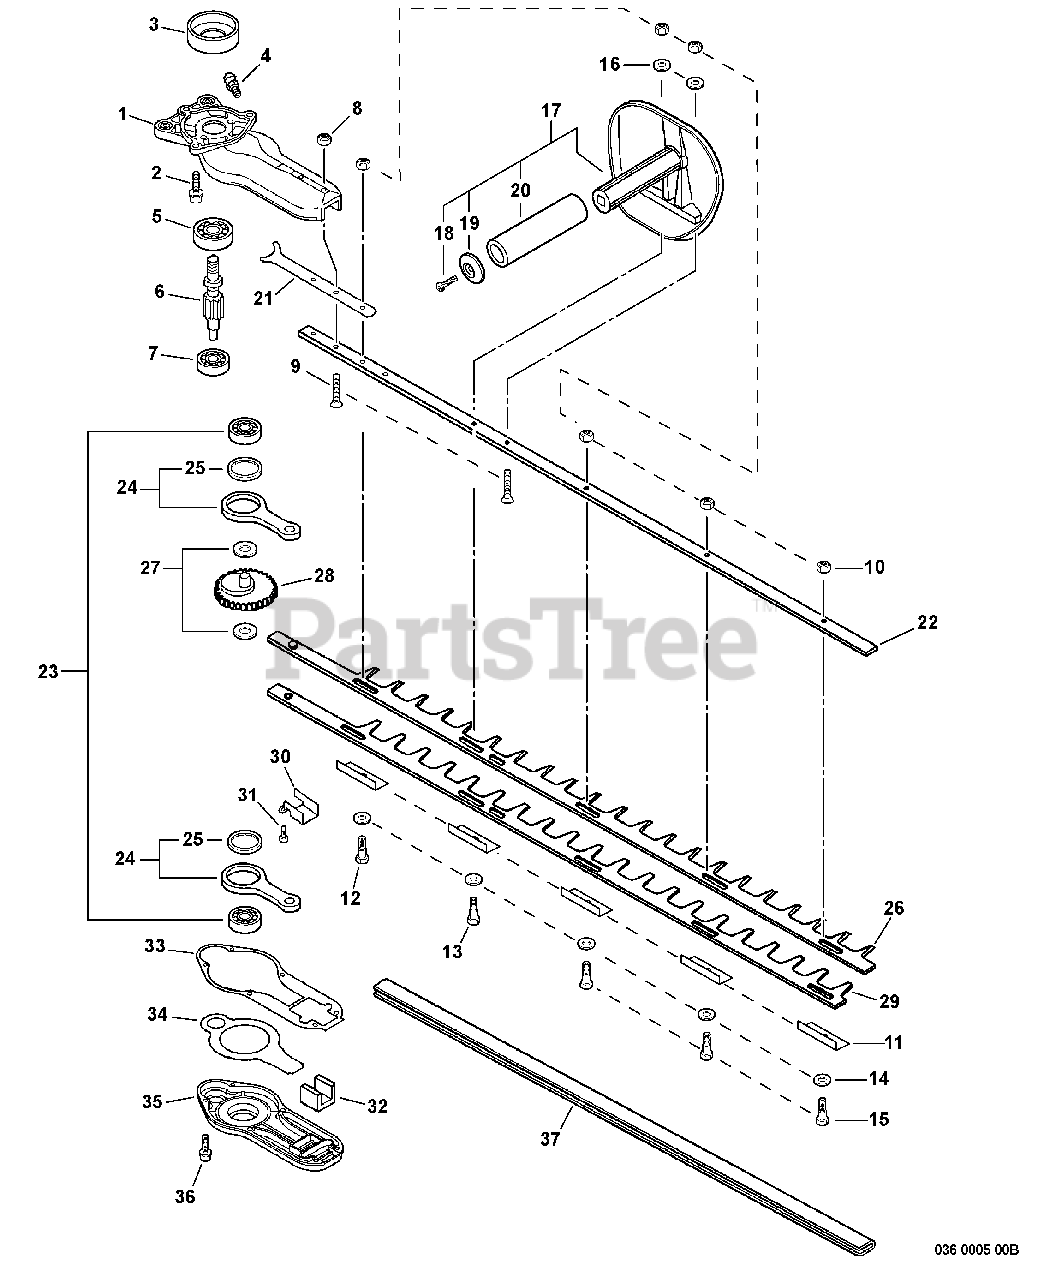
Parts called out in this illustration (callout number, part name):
1	CASE, GEAR - UPPER
2	BOLT 6×18
3	DRUM, CLUTCH
4	FITTING, GREASE
5	BEARING, BALL 6200
6	GEAR, SPUR
7	BEARING, BALL 608ZZ
8	NUT, FLANGE M6
9	BOLT 6×30
11	GUIDE, BLADE
12	BOLT 6×25
13	BOLT 6×40
15	BOLT 6×22
16	WASHER 6.5×13×1
17	HANDLE ASSY, FRONT
18	SCREW 5×14
20	GRIP, HANDLE
21	PLATE, EYE
22	SUPPORT, BLADE 30"
23	BEARING, BALL 6200
24	ROD, CONNECTING
25	BEARING, NEEDLE 30
26	BLADE, UPPER 30"
27	WASHER, THRUST 10
28	GEAR, SPUR
29	CUTTER, 30" LOWER
30	GUIDE, BLADE
31	BOLT 4×16
33	GASKET, GEAR CASE
34	PLATE, GEAR CASE
35	COVER, GEAR CASE
36	BOLT 4×16
37	SCABBARD
